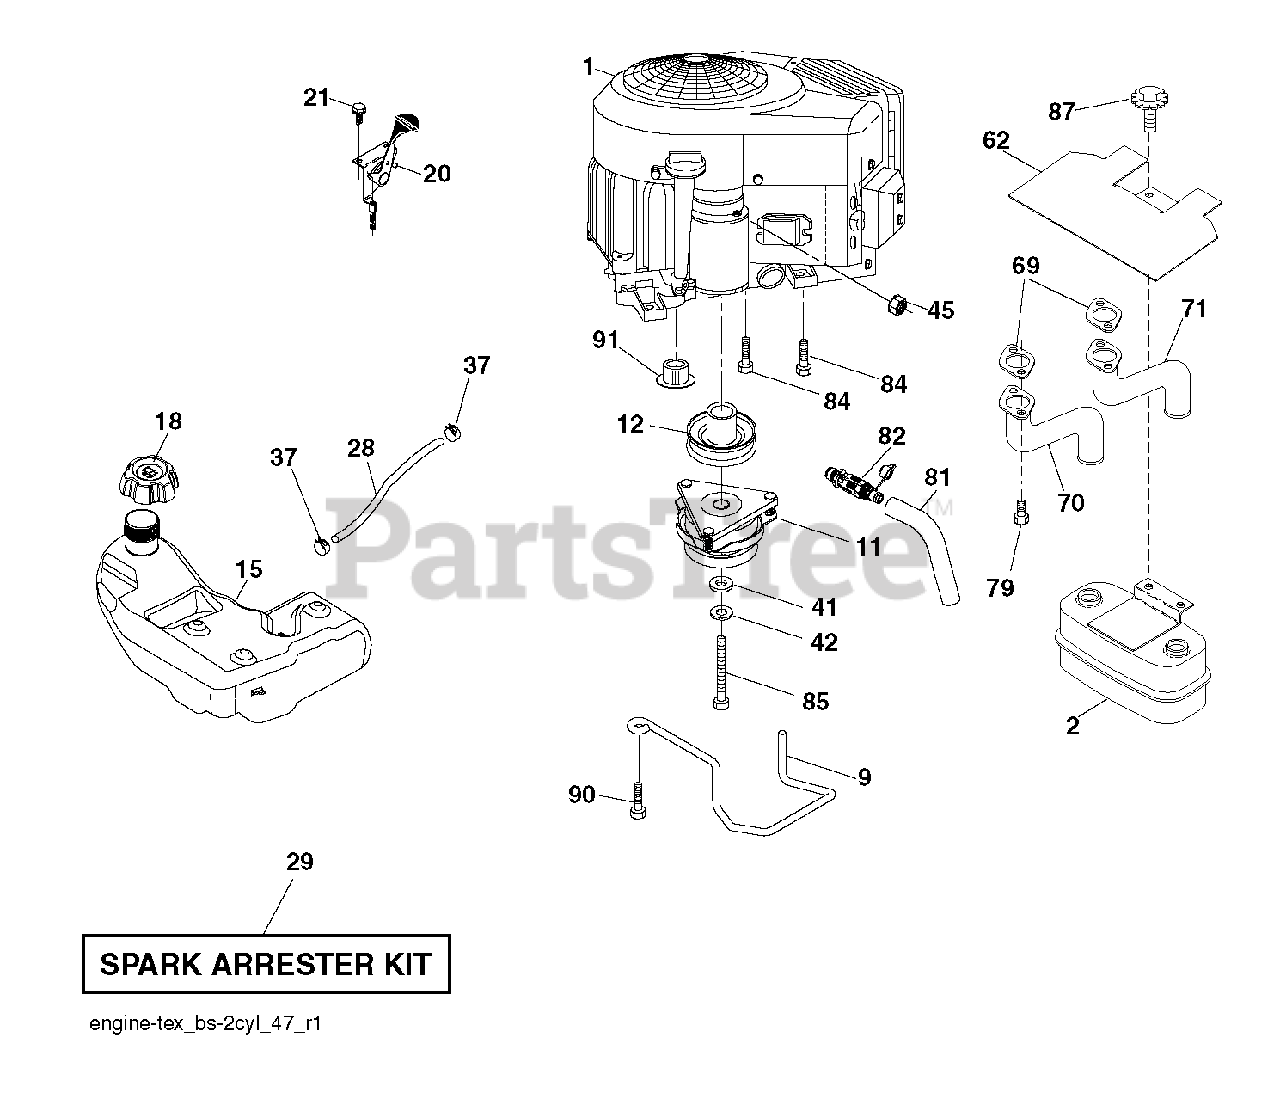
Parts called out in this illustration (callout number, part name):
2	MUFFLER.TWIN.CYL.LOW.TONE
9	KEEPER.BELT.ENGINE.4.2
11	CLUTCH ELECTRIC
12	PULLEY ENGINE
15	TANK.FUEL.4GAL
18	CAP.ASM.FUEL.TANK.3"BLACK
20	CONTROL.TH/CK.COBRA.B&S.TWN.
21	SCREW.#10 X 0.750.BOS THREAD
28	LINE.FUEL.20
29	ARRESTER SPARK (OPTIONAL)
37	HOSE CLAMP
42	LOCKWASHER
45	NUT
62	SHIELD.HEAT.MUFFLER
69	GASKET.MUFFLER
70	TUBE MANIFOLD LH
71	EXHAUST TUBE RH
79	SCREW.SOCKET.HEAD.5/16-18
81	TUBE, DRAIN OIL ASM.
82	VALUE.OIL.DRAIN
84	SCREW.3/8-16
85	BOLT HEX 7/16-20 X 3.75 GR. 5
87	BOLT, 5/16-18 X 1 3/4
90	SCREW 3/8-16X1
91	BUSHING.1.375OD
